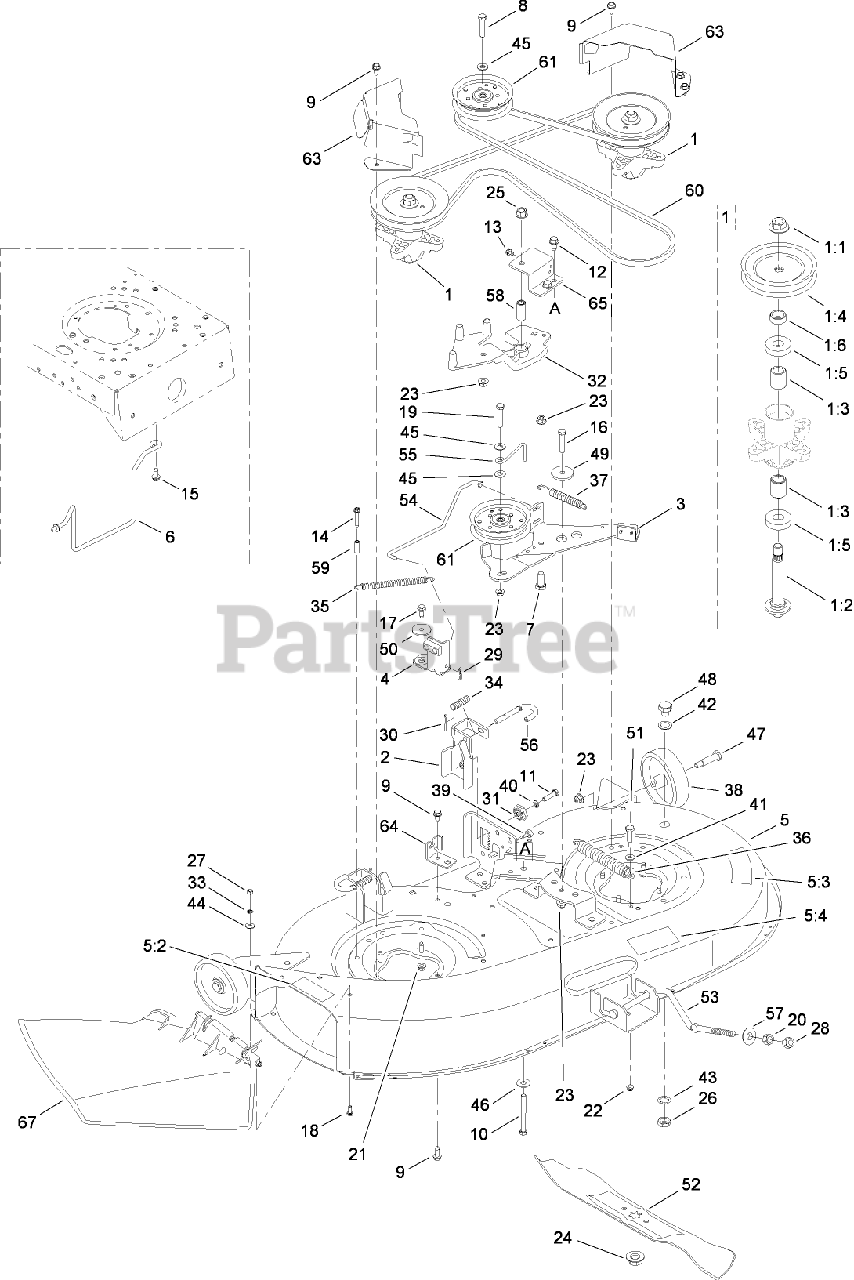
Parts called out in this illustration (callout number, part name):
1	SPINDLE ASM
1:1	NUT-LOCK, FLANGE
1:2	SHAFT-SPINDLE
1:3	SPACER
1:4	PULLEY-DECK
1:5	BEARING-BALL
1:6	SPACER
2	LH HANGER BRACKET ASM
3	DECK BRAKE ASM
4	BRAKE ASM
5	DECK AND DECAL ASM
5:2	DECAL-DANGER
5:3	DECAL-DANGER
5:4	DECAL-ROUTING, BELT
6	ROD-KEEPER, BELT
7	SCREW-HH
8	SCREW-HH
9	SCREW-TAP
10	SCREW-HH
11	SCREW-HH
12	SCREW-HWHTF
13	SCREW-TAP
14	SCREW-HWH
15	SCREW-HWH
16	SCREW-HH
17	SCREW-HH
18	SCREW-HH
19	SCREW-HH
20	NUT-HEX
21	NUT-LOCK, FLANGE
22	NUT-LOCK, FLANGE
23	NUT-LOCK, FLANGE
24	NUT-LOCK, FLANGE
25	NUT-LOCK, FLANGE
26	NUT-HEX
27	NUT-HEX
28	NUT-LOCK, HEX (NYLON)
29	PIN-COTTER
30	PIN-COTTER
31	GEAR-ADJUSTMENT, DECK
32	BRACKET-IDLER
33	RETAINER-BOLT
34	SPRING-COMPRESSION
35	SPRING-EXTENSION
36	SPRING-EXTENSION
37	SPRING-EXTENSION
38	WHEEL-DECK, REAR
39	BUMPER
40	WASHER-LOCK
42	WASHER-FLAT
43	WASHER-LOCK
44	WASHER-SPRING
45	WASHER-FLAT
46	WASHER-FLAT
47	BOLT-SHOULDER
49	SPACER-SHOULDER
50	SPACER-SHOULDER
51	BOLT-SHOULDER
53	ROD-DECK, FRONT ADJUSTMENT
54	ROD-BRAKE
55	ROD-KEEPER, BELT
56	PIN-HANDLE, DECK RELEASE
57	CUP-PIVOT, LIFT
58	SPACER
59	SPACER
60	BELT-V TYPE
61	PULLEY-IDLER
63	COVER-BELT
65	SUPPORT-BRACKET, PIVOT
67	DISCHARGE CHUTE ASM
